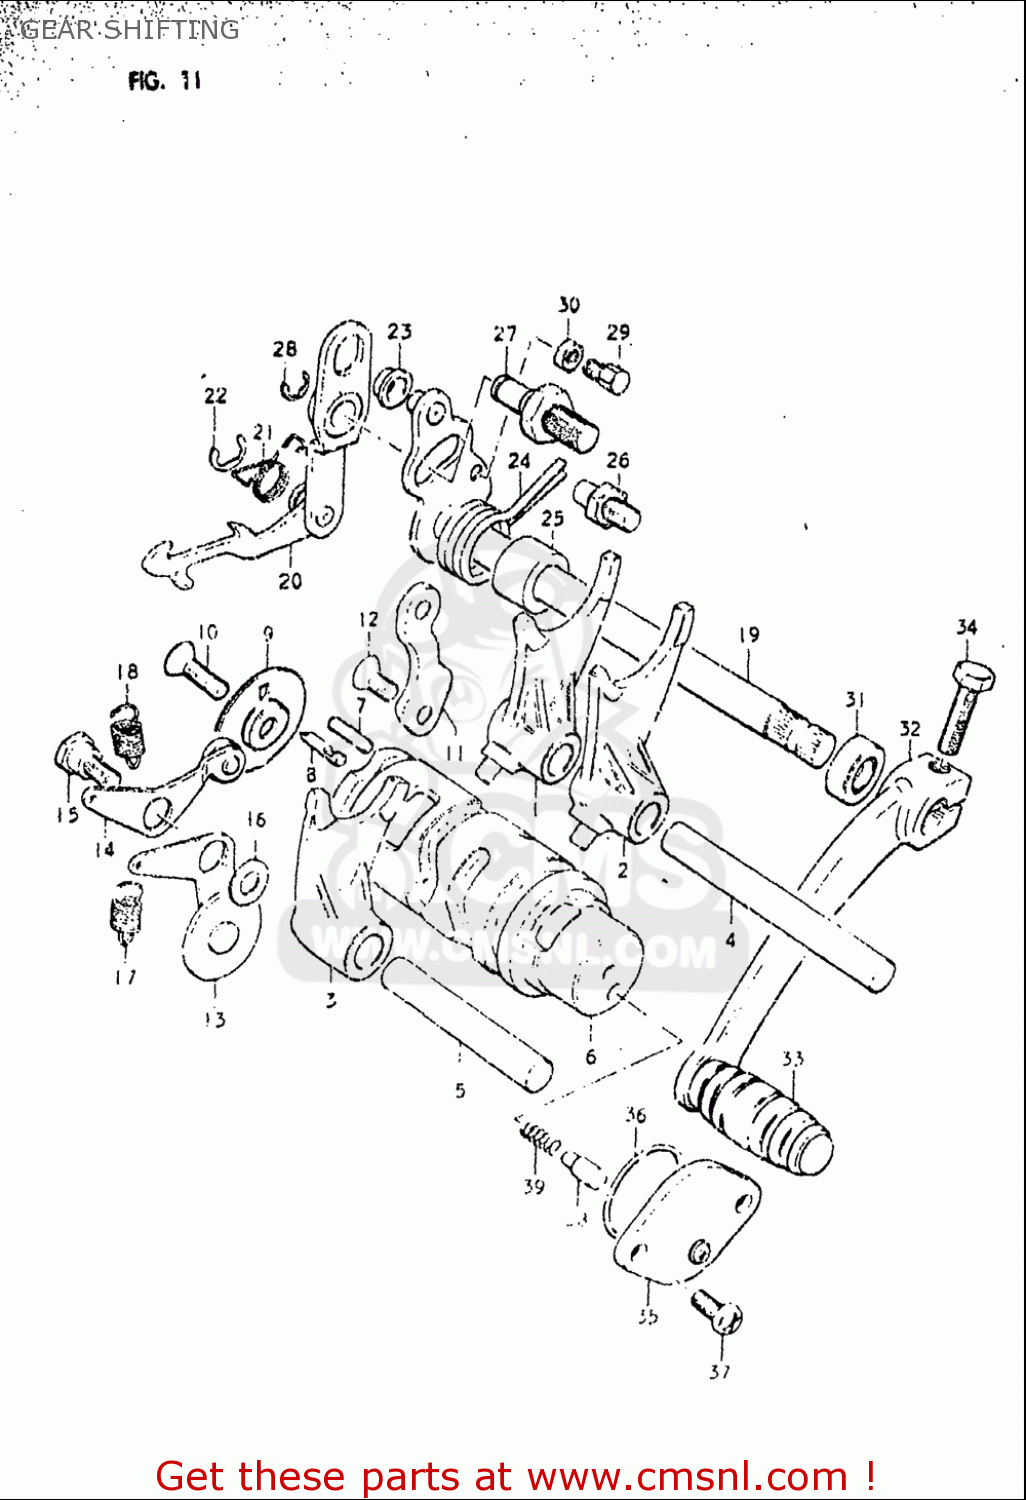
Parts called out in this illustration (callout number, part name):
1	FORK,GEAR SHIFT NO.1
2	FORK,GEAR SHIFT NO.2
4	SHAFT,GEAR SHIFT FORK
5	SHAFT,GEAR SHIFT FORK NO.2
6	CAM,GEAR SHIFT
7	PIN(4X15.8)
8	PIN
9	RETAINER,GEAR SHIFT CAM DR PIN
10	SCREW
12	SCREW
13	STOPPER,GEAR SHIFT CAM
14	STOPPER,GEAR SHIFT CAM NEUTRAL
15	BOLT(6X18.3)
16	WASHER
17	SPRING
18	SPRING
19	SHAFT,GEAR SHIFT
20	PAWL,GEAR SHIFT
21	SPRING
22	E-RING
23	SPACER(7X10X5)
24	SPRING
25	SPACER(12X20X15.3)
26	STOPPER,GEAR SHIFT ARM
28	E RING
30	NUT
31	SEAL,OIL (12X22X9)
32	LEVER ASSEMBLY,GEAR SHIFTING
33	RUBBER,GEAR SHIFT PEDAL
34	BOLT
35	BODY,GEAR SHIFT SWITCH
36	O RING(D:2.4,ID:26.2)
37	SCREW
38	PIN(5X15.5)
39	SPRING
